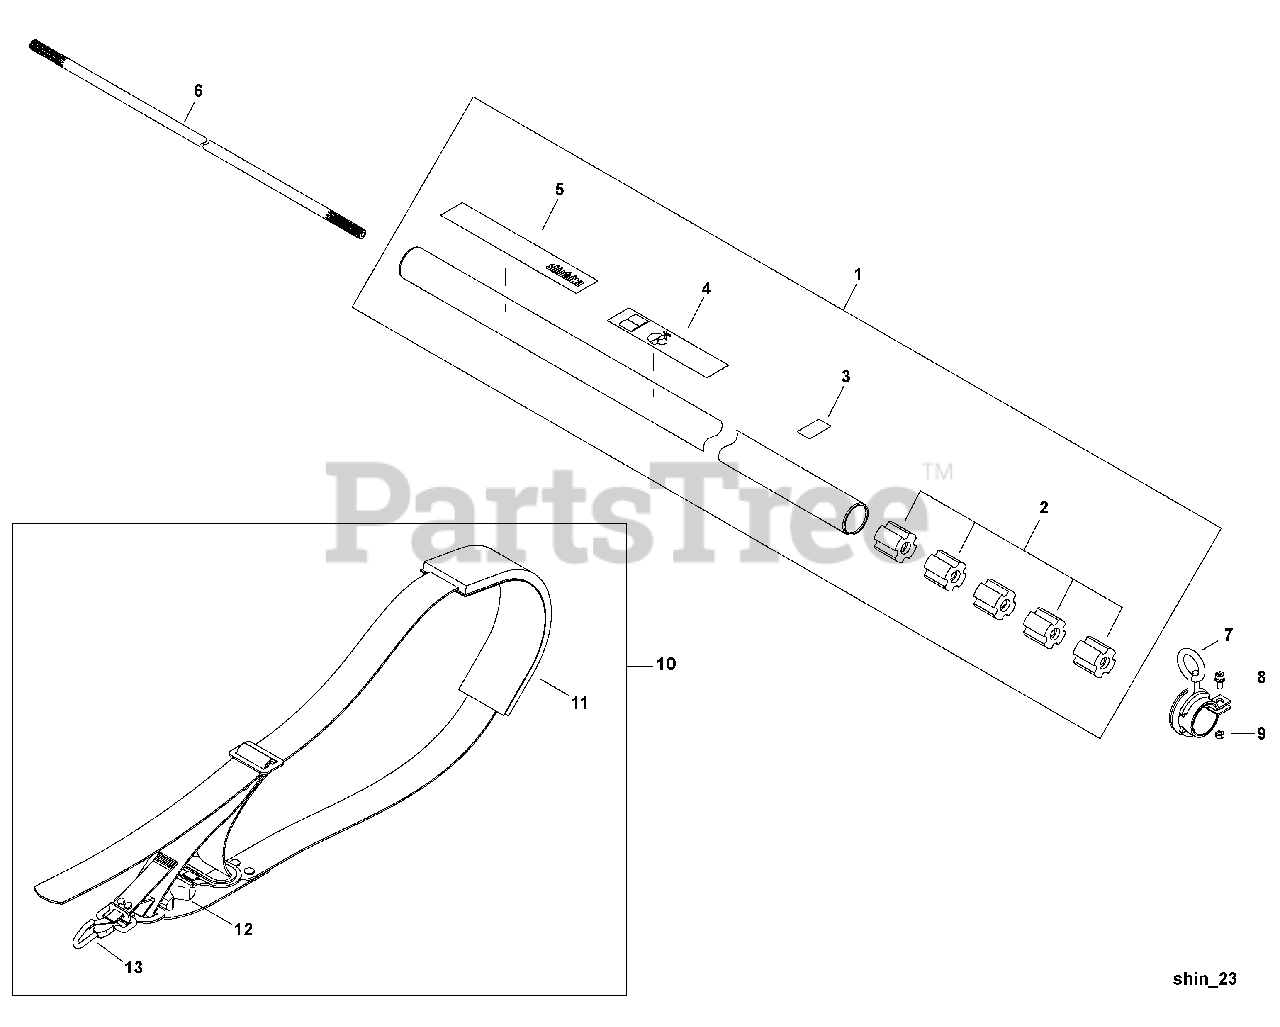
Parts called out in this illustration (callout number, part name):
1	MAIN PIPE ASSY
2	BUSHING
3	LABEL, HANDLE
4	LABEL, CAUTION (NON-BLADE CAPABLE)
5	LABEL, SHINDAIWA PROFESSIONAL
6	MAINSHAFT
7	HANGER, SWIVEL
8	BOLT M5×12
9	NUT M5
10	HARNESS ASSY
11	PAD, SHOULDER
13	HOOK, SNAP
